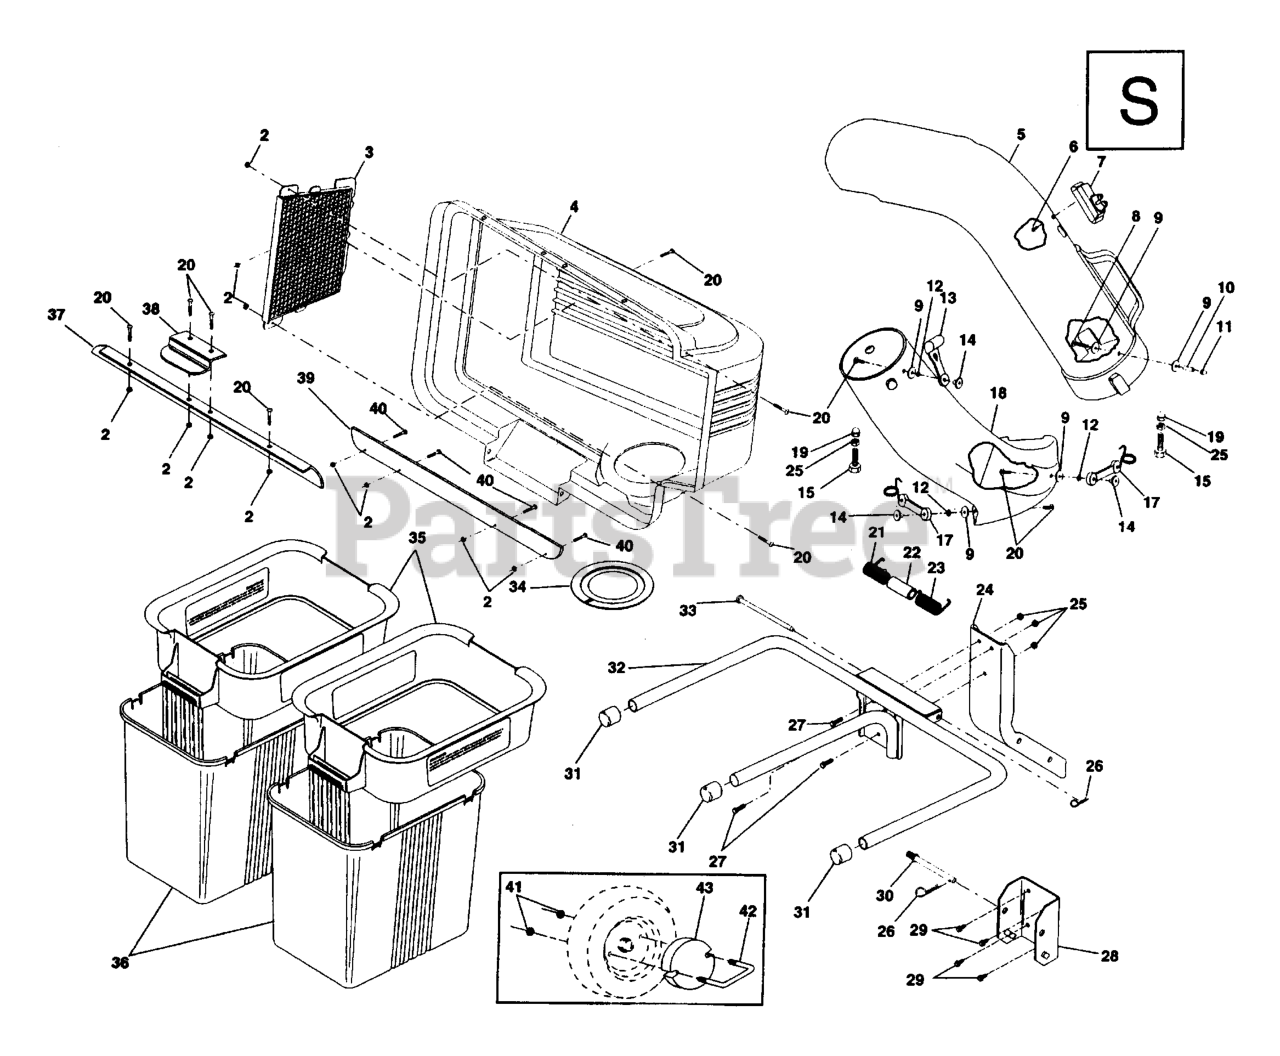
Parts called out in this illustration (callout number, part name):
3	COVER SCREEN
4	COVER BAGGER TOP
5	CHUTE.UPPER.BAGGER.36"
7	INDICATOR DUMP BAG
8	SCREW
9	WASHER
11	NUT
12	LOCKWASHER #10
13	LATCH.HOOD.
14	WELDNUT
15	BOLT GT
17	LATCH ASSEMBLY
18	CHUTE LOWER 36"
20	SCREW.10-24X5/8
21	SPRING COVER LH
22	SPACER.COVER.BAGGER
23	SPRING COVER RH
24	SUPPORT POST
26	RETAINER-SPRNG RB
27	BOLT
28	MTG BRACKET
29	Screw 5/16-18 x 1/2 Hex, Self Tapping 5/16-18 x 1/2
30	SUPPORT POST PIN
31	TUBING PLUG
32	BAGGER FRAME
33	HINGE PIN
34	GASKET.COVER.BAGGER
35	CONTAINER TOP
36	CONTAINER BOTTOM
37	SEAL.COVER.BAGGER
38	LATCH CER38
39	SEAL STRIP
40	SCREW
41	NUT
43	WEIGHT, FRT WHEEL
